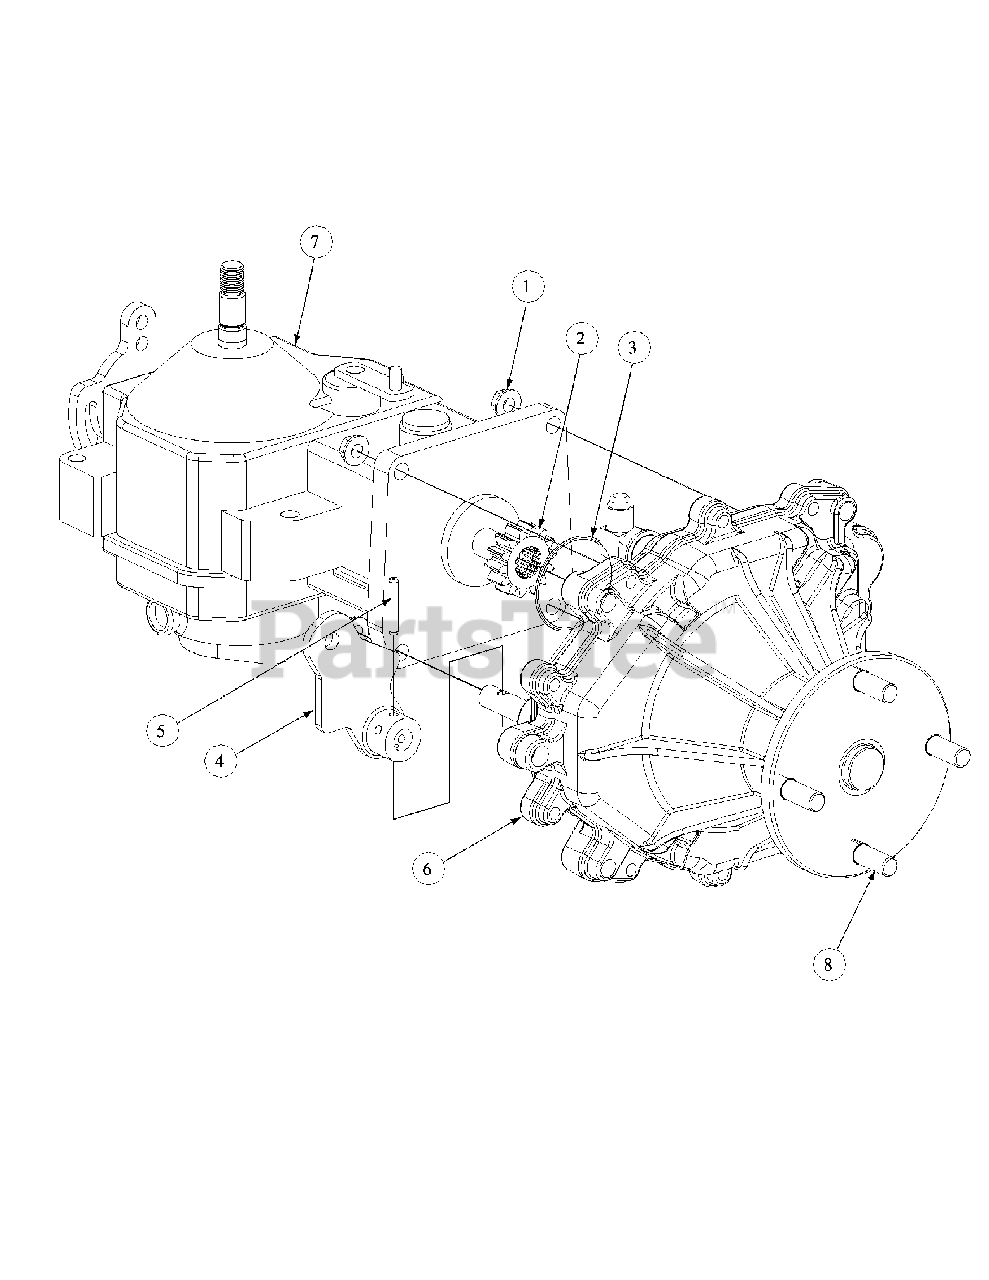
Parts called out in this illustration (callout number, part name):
1	Hex Flange, Lock Nut, 5/16-18
2	Gear, Spur, 14T
3	O-Ring, 2.00 x .070
4	Lever, Bracket, Park
5	Pin, Spirol, 3/16 x 1.25 HD
6	Transmission Assembly
8	Rib Neck Stud, 1/2-20
